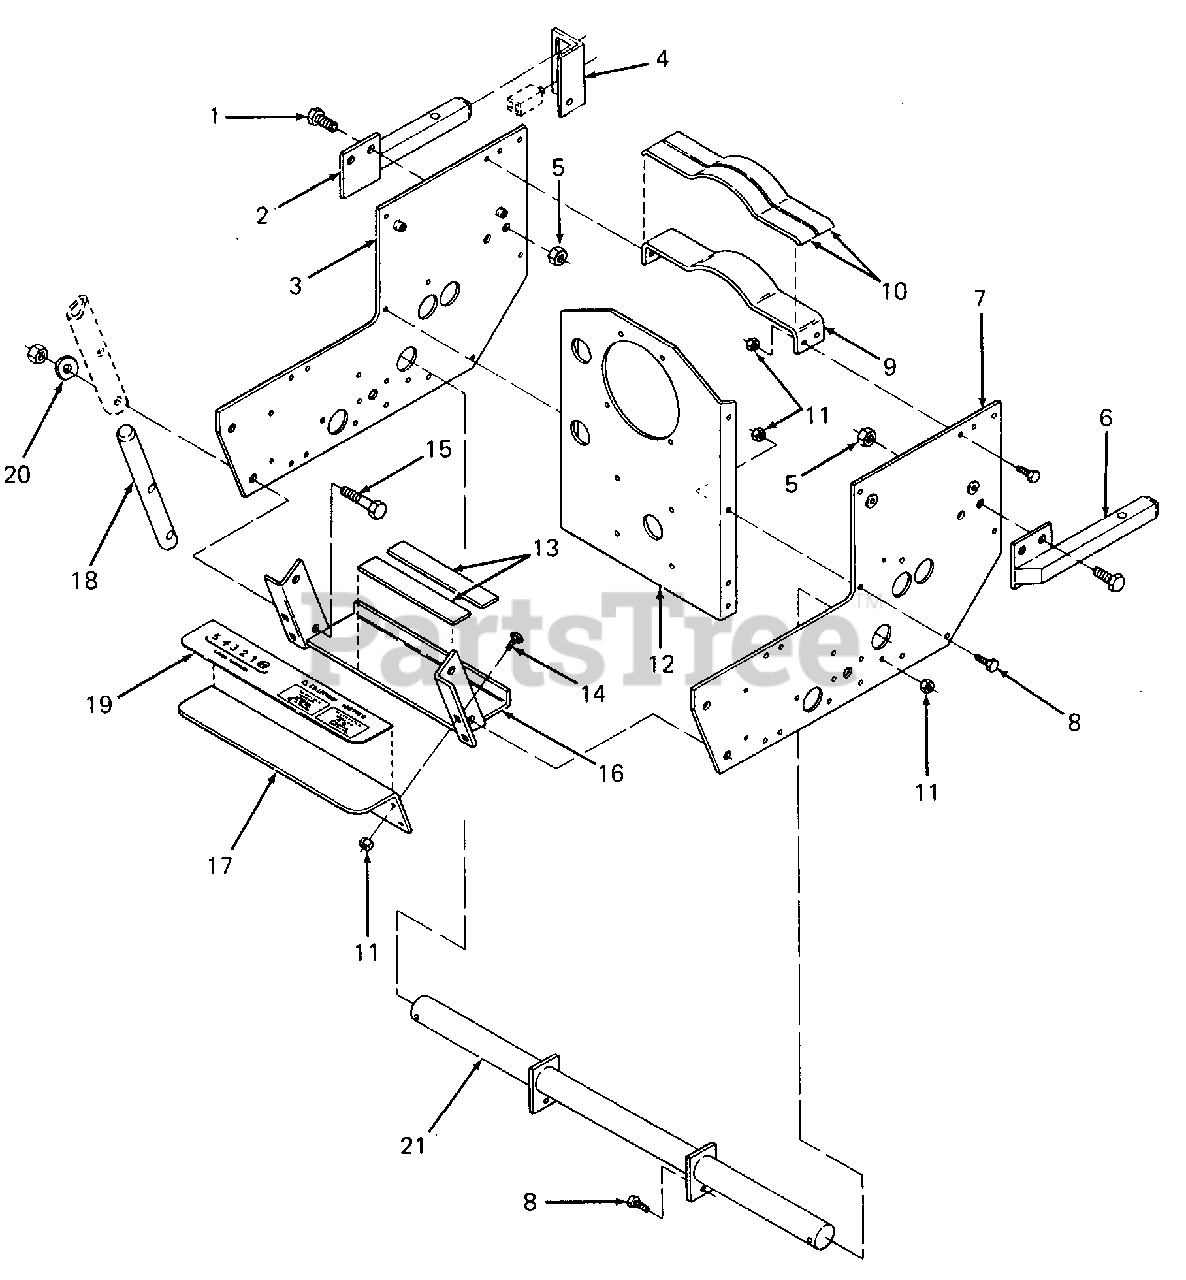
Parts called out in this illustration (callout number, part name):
1	Screw, Hex Cap, 1/2-13 x 1.25 Lg GR5
3	Frame Side, LH
4	Bracket, Bypass Switch
5	Nut, Hex Center, Lock, 1/2-13
7	Frame Side, RH
8	Screw, Hex Cap, 3/8-16 x 1.0 Lg GR5
9	Brace, Fuel Tank
10	Pad, Fuel Tank
11	Nut, Hex Center Lock, 3/8-16
12	Plate, Engine Mtg
13	Pad, Battery
14	Carriage Bolt, 3/8-16 X 1.0 GR5
15	Screw, Hex Cap, 1/2-13 X 2.75 Lg GR2
16	Box, Battery
17	Cover, Battery Box
18	Shaft, Handlebar Support
19	Decal, Gear Shift
20	Washer, Belleville, 1/2
